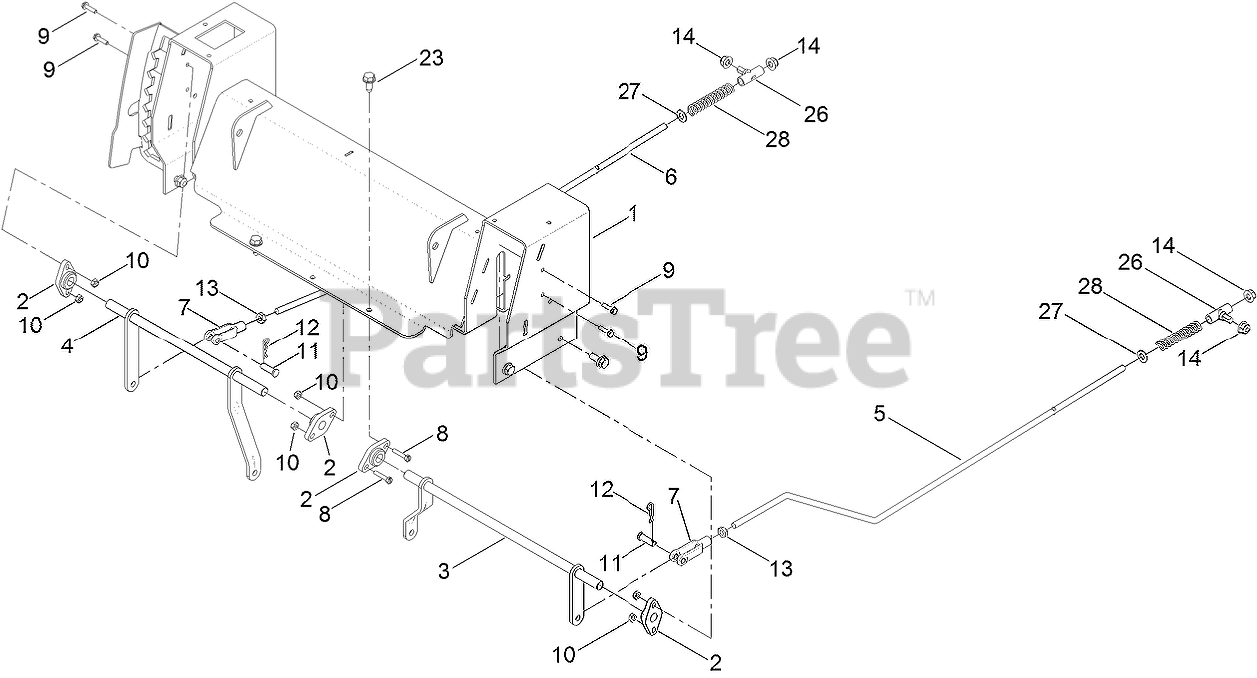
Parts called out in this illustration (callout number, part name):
1	BOX-CONTROL, WIDE
2	BEARING-FLANGE
3	BELLCRANK-LH
4	BELLCRANK-RH
5	ROD-HYDRO, LH
6	ROD-HYDRO, RH
7	YOKE-ADJUSTABLE
9	SCREW-HWH
10	NUT-LOCK, NI
11	PIN-CLEVIS
12	PIN-COTTER
13	NUT-JAM
13	SCREW-HHF
14	NUT-HF, NI
23	SCREW-HWHTF
26	MOUNT-ROD, HYDRO
27	WASHER-PLAIN
28	SPRING-RETURN, NEUTRAL
